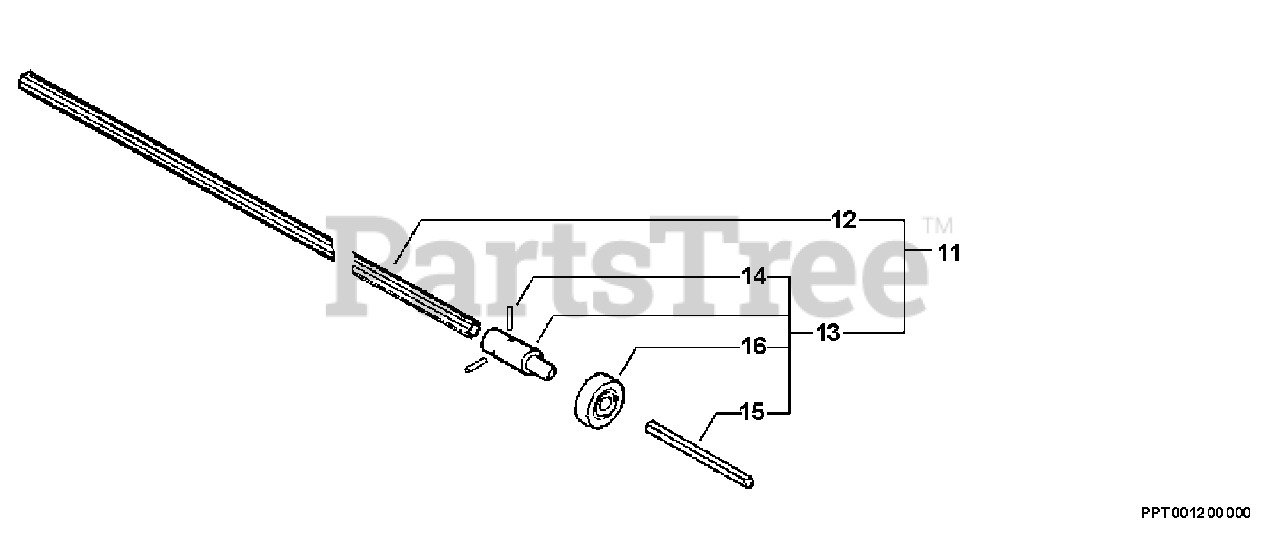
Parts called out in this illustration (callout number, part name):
11	SHAFT ASSY, DRIVE
12	DRIVESHAFT
13	CONNECTOR, DRIVE SHAFT
16	BEARING, BALL 6002 DDU
